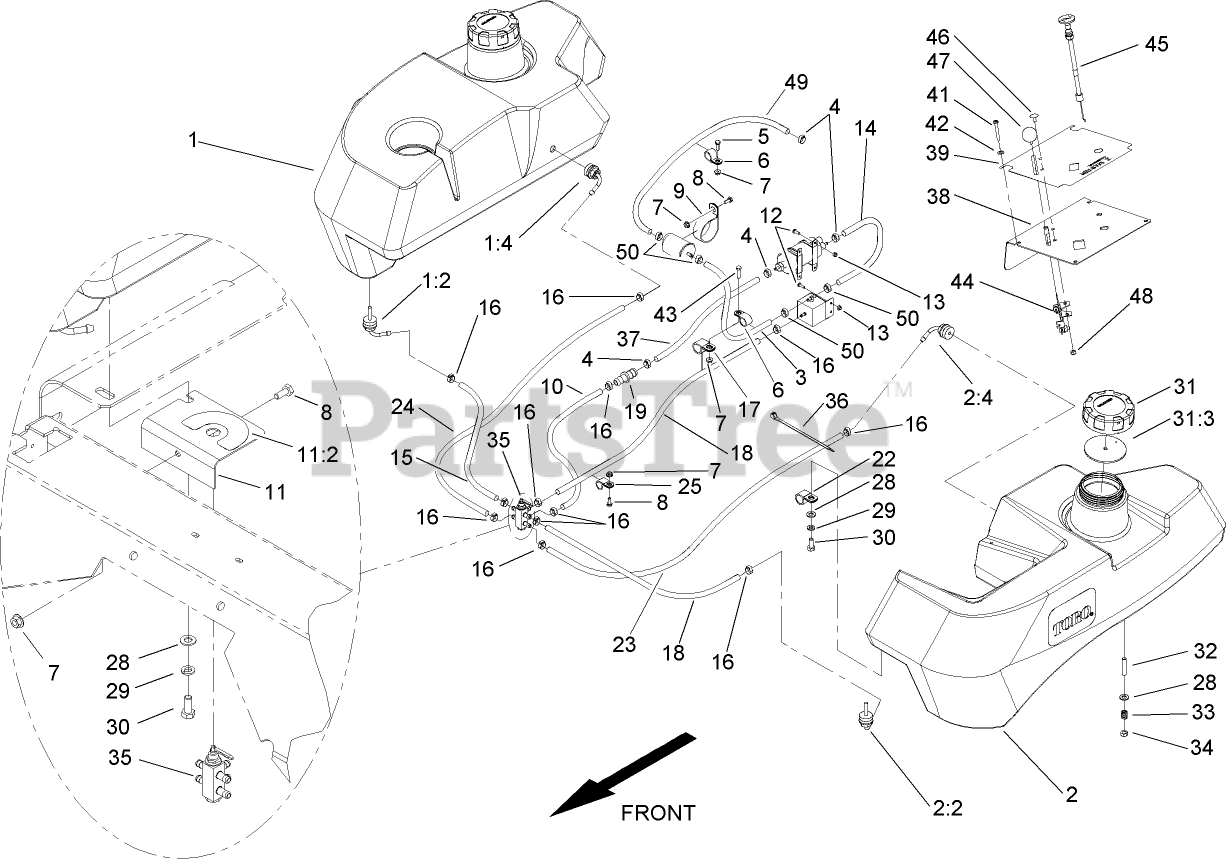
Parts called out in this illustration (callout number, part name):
1	RH Fuel Tank ASM
1:2	FITTING-FUEL, BULKHEAD
1:4	Fitting-Fuel, Bulkhead
2	LH Fuel Tank ASM
2:2	FITTING-FUEL, BULKHEAD
2:4	Fitting-Fuel, Bulkhead
3	Hose-Fuel
4	CLAMP-HOSE, FUEL
5	SCREW-HH
6	CLIP-LOOM
7	NUT-HF
8	SCREW-HH
9	CLIP-LOOM
10	HOSE-FUEL
11	Fuel Valve Bracket Asm
11:2	DECAL-VALVE, FUEL
12	SCREW-PPH
13	NUT-LOCK, NI
14	Hose-Fuel
15	HOSE-FUEL
16	CLAMP-HOSE, FUEL
17	CLIP-LOOM
18	HOSE-FUEL
19	Connector
23	Hose-Fuel
24	Hose-Fuel
25	CLIP-LOOM
28	WASHER-PLAIN
29	WASHER-LOCK
30	SCREW-HH
31	GAS CAP ASM
31:3	GASKET-CAP, GAS
33	SPRING-TANK, FUEL
34	NUT-LOCK, NI
35	VALVE-FUEL, DUAL FLOW
36	TIE-CABLE
37	HOSE-FUEL
38	PANEL-CONTROL
39	Decal-Panel, Control
42	WASHER-SPRING
43	SCREW-HH
44	CABLE-THROTTLE
45	Control-Choke, Push / Pull
46	BOLT-CARR
47	KNOB-BALL
48	NUT-LOCK, NI
49	Hose-Fuel
